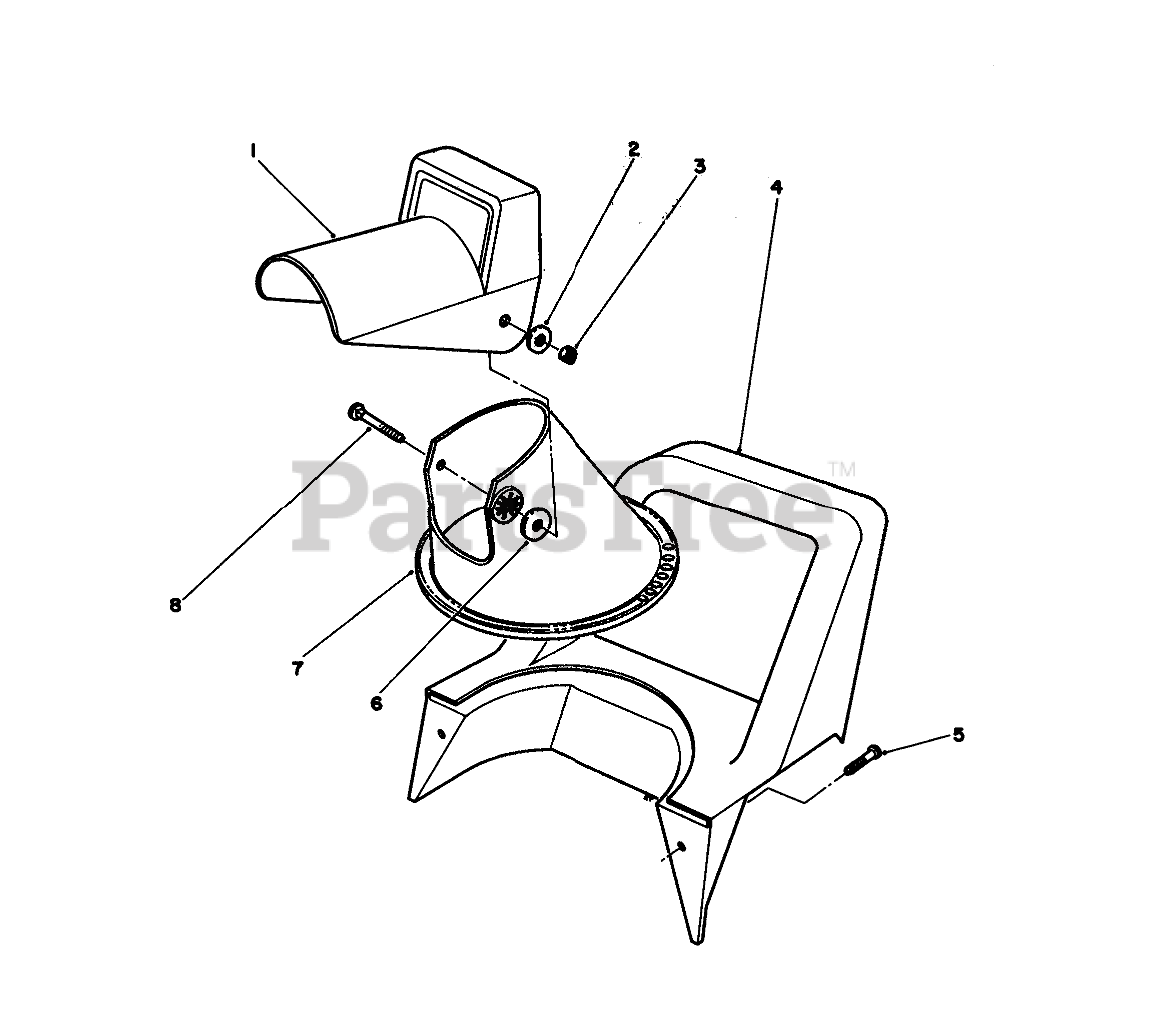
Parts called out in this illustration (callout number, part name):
1	Chute-Deflector
2	WASHER-FLAT
3	NUT-LOCK, NI
4	Handle-Middle
5	Screw
6	WASHER-RUBBER
7	Chute-Lower
8	BOLT-CARR
